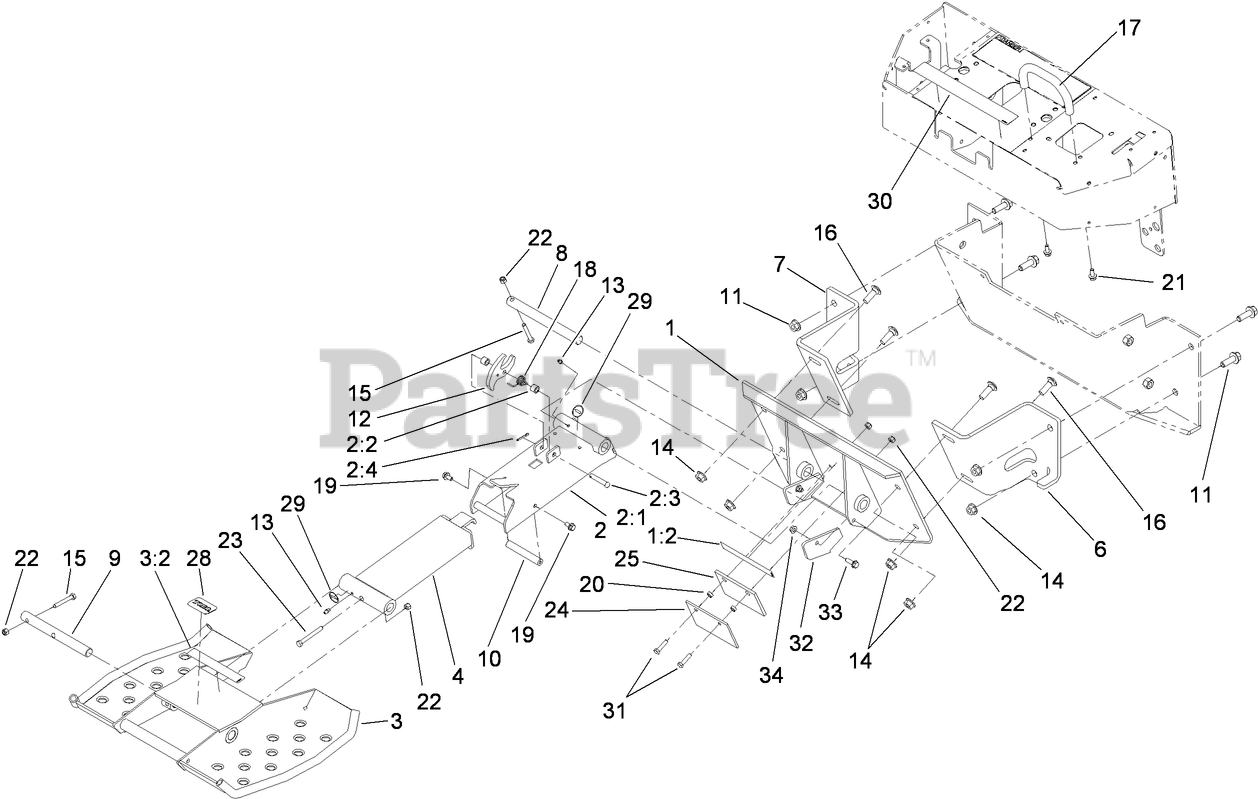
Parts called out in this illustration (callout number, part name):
1	SULKY MOUNTING PLATE ASM
1:2	DECAL-POINT, PINCH
2	LINKAGE ASM
2:1	LINKAGE-WRAPPER
2:2	SPACER
2:3	PIN-CLEVIS
2:4	PIN-COTTER
3	PLATFORM ASM
3:2	DECAL-POINT, PINCH
4	SLIDE ASM
6	PLATE-MOUNTING, RH
7	PLATE-MOUNTING, LH
8	PIN-UPPER
9	PIN-LOWER
10	ROD-CLAMP
11	SCREW-HHF
12	LATCH-PLATFORM
13	FITTING-GREASE
14	NUT-HHF
15	SCREW-HH
16	SCREW-CARR
17	BAR-REFERENCE
18	SPRING-TORSION, RH
19	SCREW-HHF
20	SPACER
21	SCREW-HHF
22	NUT-LOCK, NI
23	SCREW-HH
24	PLATE-PUSH
25	PAD-RUBBER
28	Decal
29	DECAL-GREASE
30	DECAL-WARNING/INSTRUCTIONAL
31	SCREW-HH
32	PLATE-BUMPER
33	SCREW-HHF
34	NUT-HF
